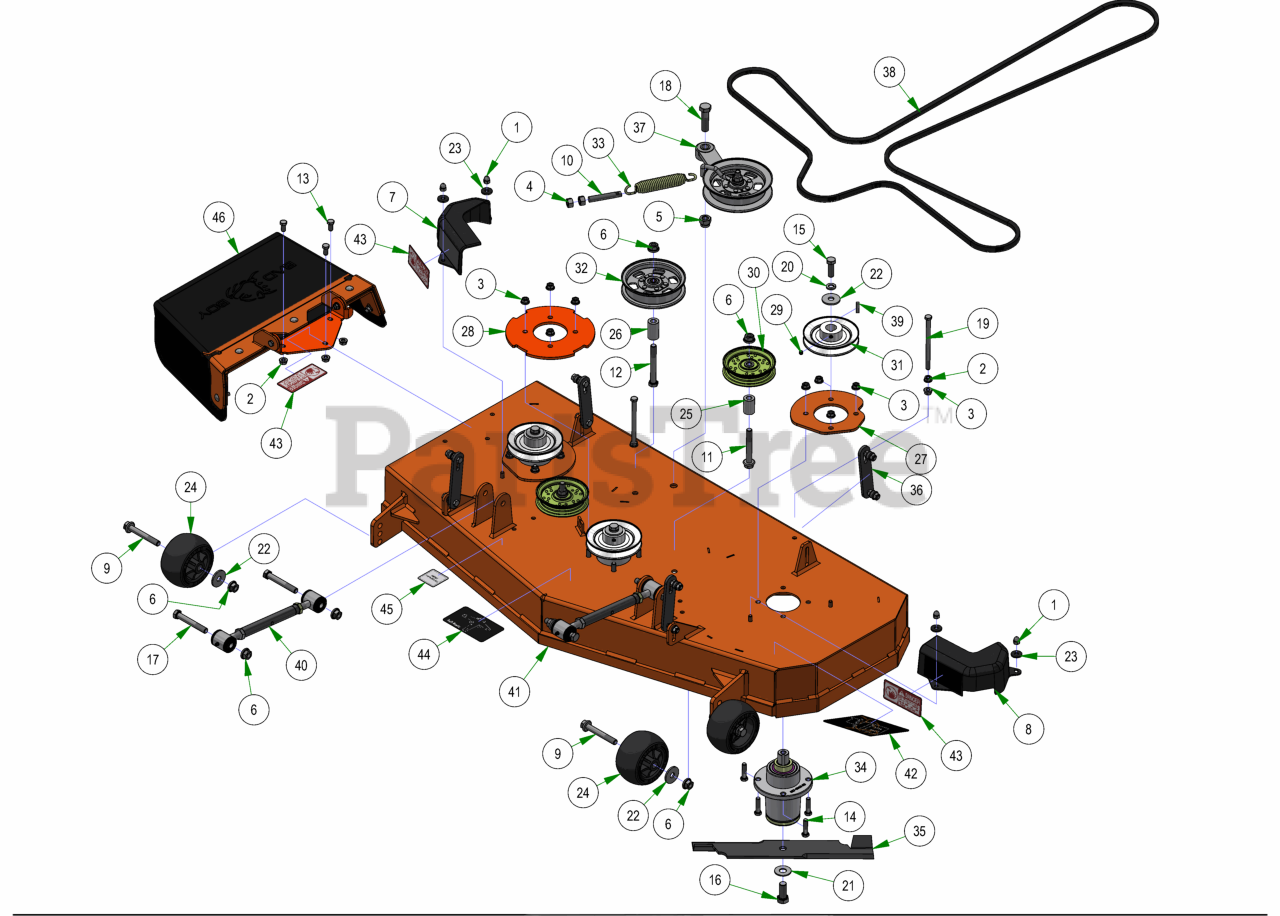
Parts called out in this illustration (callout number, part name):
1	5/16-18 ACORN NUT HIGH-CROWN ZC
2	3/8-16 HEX SERRATED FLANGE NUT HARD/ZINC
3	3/8-16 NYLON INSERT FLANGE LOCKNUT (GR.F) ZINC
4	1/2-13 HEX NUT ZINC
5	5/8-11 NYLON INSERT LOCKNUT ZINC
6	1/2-13 NYLON INSERT FLANGE LOCKNUT ZINC
7	Pulley Cover Chute Side
8	Pulley Cover Non-Chute Side
9	1/2-13 X 90MM HEX FLANGE BOLT W/SHOULDER (GR.8) ZINC
10	All Thread
11	1/2-13 X 3-1/2 HEX FLANGE BOLT (GR.8) ZINC
12	1/2-13 X 4 HEX CAP SCREW (GR.8) ZINC YELLOW
13	3/8-16 X 3/4 HEX CAP SCREW (GR.5) ZINC
14	3/8-16 X 1-1/2 HEX CAP SCREW (GR.5) ZINC
15	1/2-20 X 1-1/2 HEX CAP SCREW (GR.5) ZINC
16	5/8-18 X 1-1/2 HEX CAP SCREW (GR.8) ZINC YELLOW
17	1/2-13 X 3-1/2 HEX CAP SCREW (GR.5) ZINC
18	5/8-11 X 2-1/4 HEX CAP SCREW (GR.5) ZINC
19	3/8-16 X 5-1/2 HEX CAP SCREW (GR.5) ZINC
20	1/2 SPLIT LOCKWASHER (GR.8) ZINC/YELLOW
21	5/8 USS FLAT WASHER (1-3/4" OD) GR.8 ZINC YELLOW
22	1/2 BELLEVILLE WASHER (1-5/8 OD X .140 THK) ZINC
23	.360 ID X .983 OD X .120 THICK FLAT WASHER NYLON BLACK
24	Deck Wheel
25	.502 ID X .750 OD X 1.500 Long Spacer
26	1 3/4" Pulley Spacer
27	42&48 Deck Spindle Support Plate
28	Deck Spindle Support Plate
29	5/16-24 X 1/4 SOCKET SET SCREW (CUP PT) PLAIN
30	4 3/4 Idler Pulley - ABFI-76
31	5" Spindle Deck Pulley
32	5-3/4 Idler Pulley
33	Deck Idler Spring
34	Spindle Assembly
35	48" ZT/Mav/Compact Outlaw Blade with Fusion
36	Deck Hanger Assembly
37	Maverick HD & Down Deck Idler Assembly
38	B147 Deck Belt
39	1/4 X 1 SQ MACHINERY KEY 1018 STL PLN
40	2018 Maverick Turnbuckle (Top Link)
41	2025 48" x 5" Deck
42	48" Grip Deck Decal
43	Danger Decal-Spindle/Discharge
44	Deck Belt Route Decal
45	Deck Impact Patent Decal 9591803
46	ZT Chute Assembly
